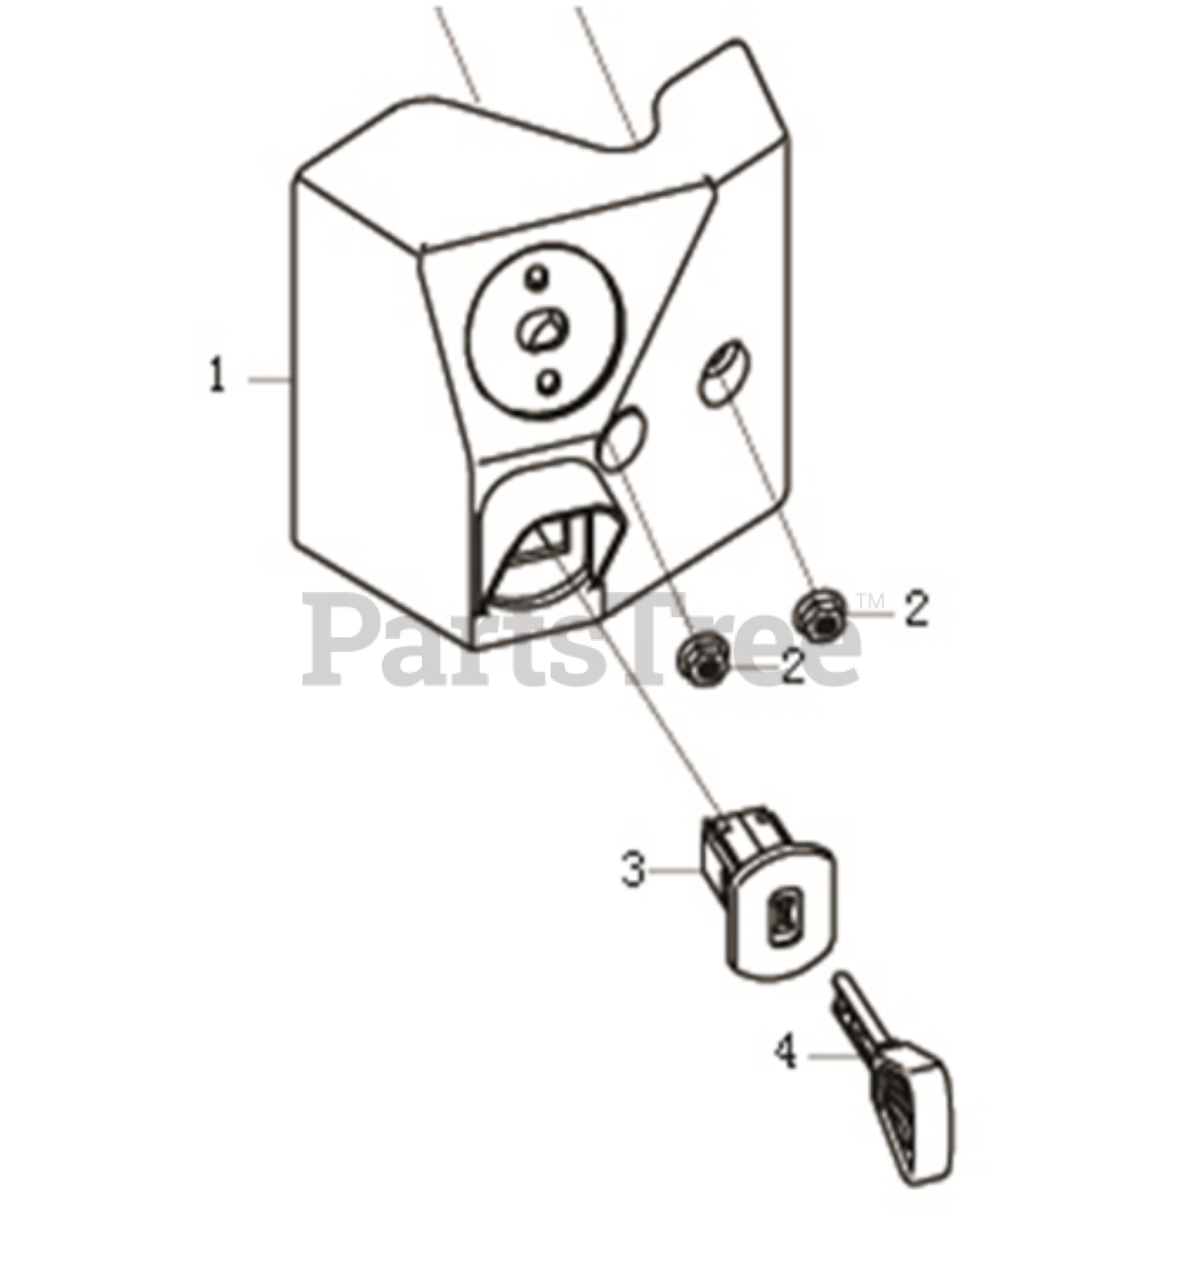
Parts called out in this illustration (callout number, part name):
1	Heater Box
2	Hexagon nut with flange
3	Stop switch
4	Switch off key
